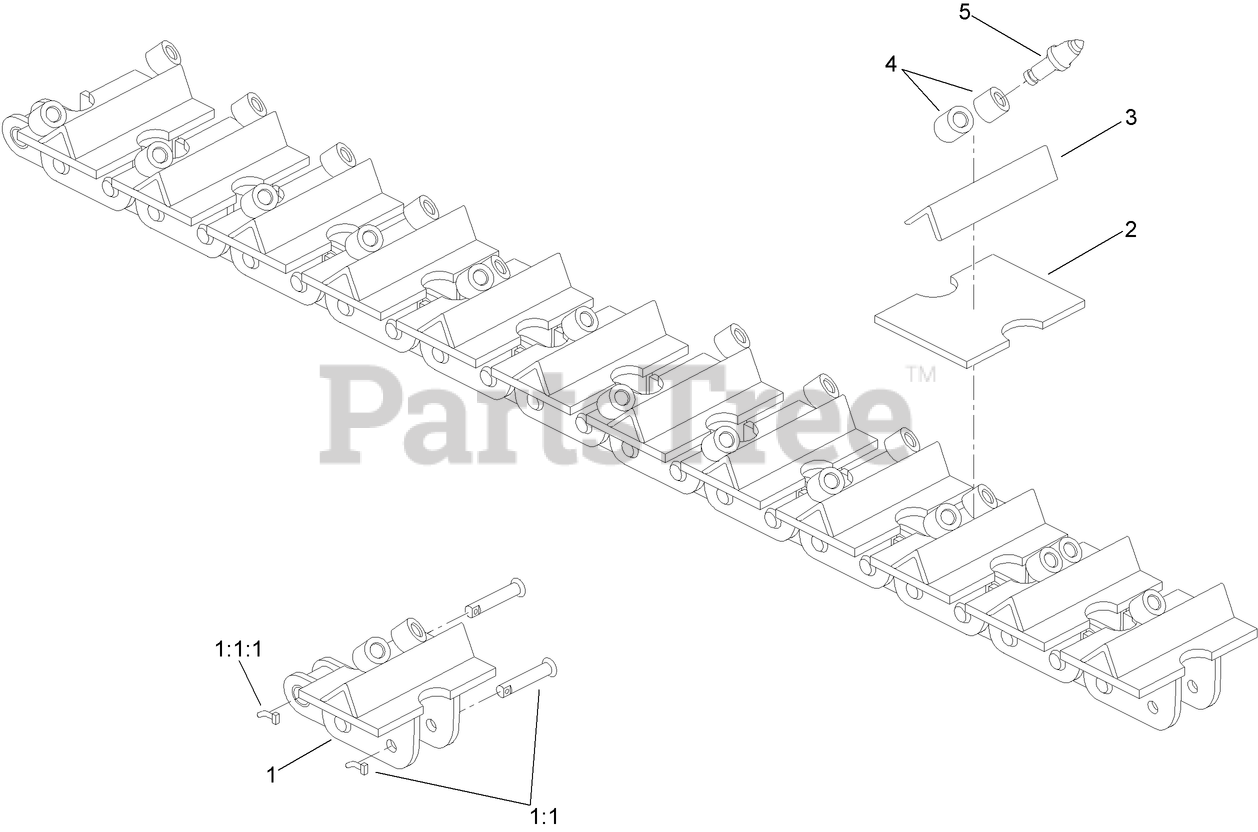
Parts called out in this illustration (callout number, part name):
1	CHAIN REPAIR LINK ASM
1:1	NOTCHED PIN AND KEEPER ASM
1:1:1	PIN-KEEPER
2	PLATE-H, WELD-ON
3	ANGLE-8 INCH
4	HOLDER-BIT
5	BIT-RETAINER, REAR
